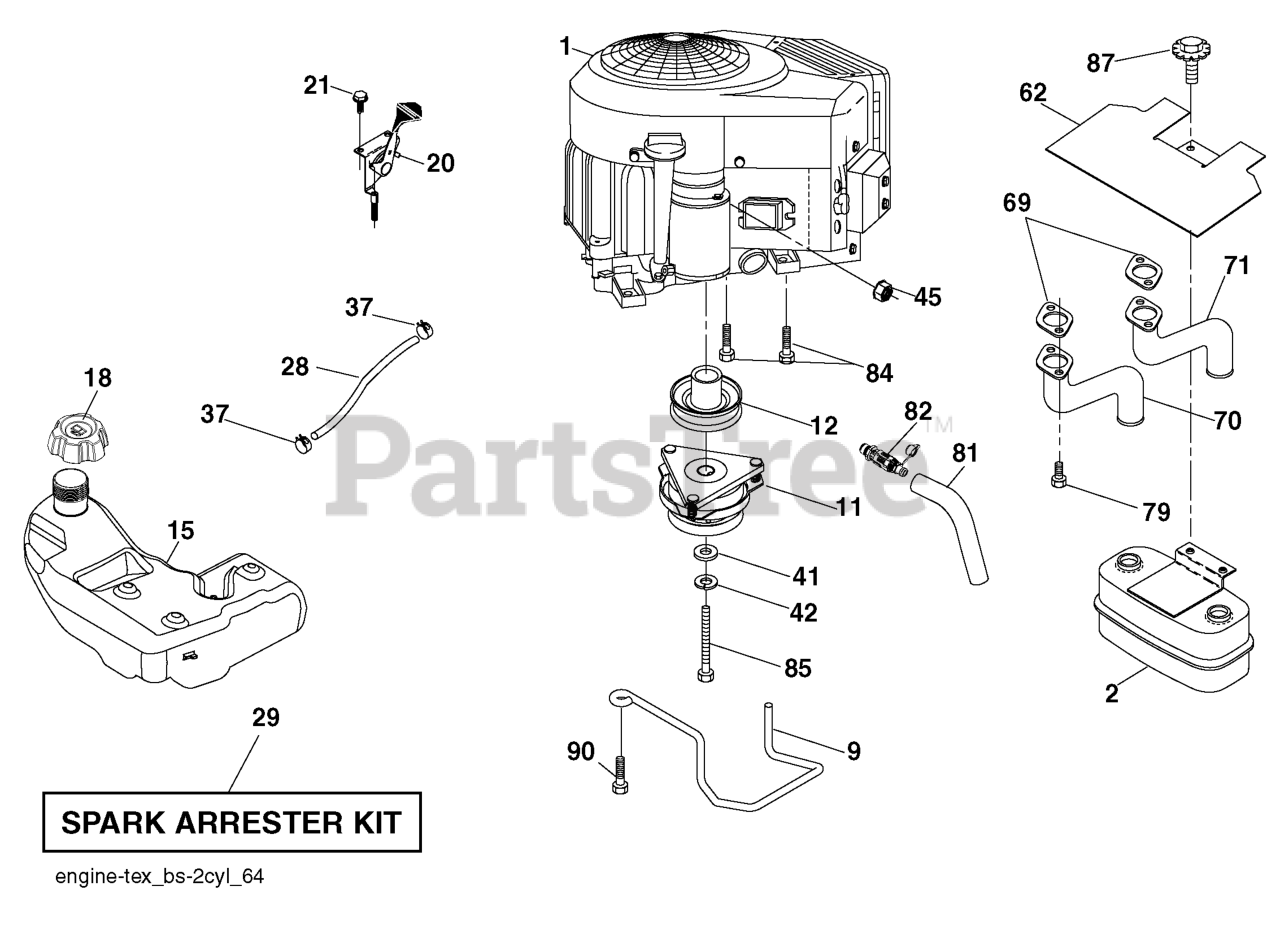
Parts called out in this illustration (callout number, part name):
2	MUFFLER.TWIN.CYL.LOW.TONE
9	KEEPER.BELT.ENGINE.4.2
11	CLUTCH.ELECTRIC.LT.48"*
12	PULLEY.ENGINE.TUFFTORQ
15	TANK.FUEL.SIDE-FILL.3.NON-EPA
18	RP CAP FUEL
20	CONTROL.TH/CK.COBRA.B&S.TWN.BK
21	SCREW.#10 X 0.750.BOS
28	LINE.FUEL.64"REAR.EMIS
29	KIT.SPARK ARRESTOR 794945 B&S
37	HOSE CLAMP
42	LOCKWASHER
45	NUT
62	SHIELD.HEAT.MUFFLER
69	GASKET.MUFFLER
70	RP.EXHAUST.TUBE.LH.BS/TWIN
71	EXHAUST.TUBE.RH.BS/TWIN
79	SCREW.SOCKET.HEAD.5/16-18
81	TUBE, DRAIN OIL ASM.
82	VALUE.OIL.DRAIN
84	SCREW.3/8-16
85	BOLT HEX 7/16-20X4-1/4"
87	BOLT.5/16-18UNCX3/4 W/SEMS.BLK
90	SCREW 3/8-16X1
